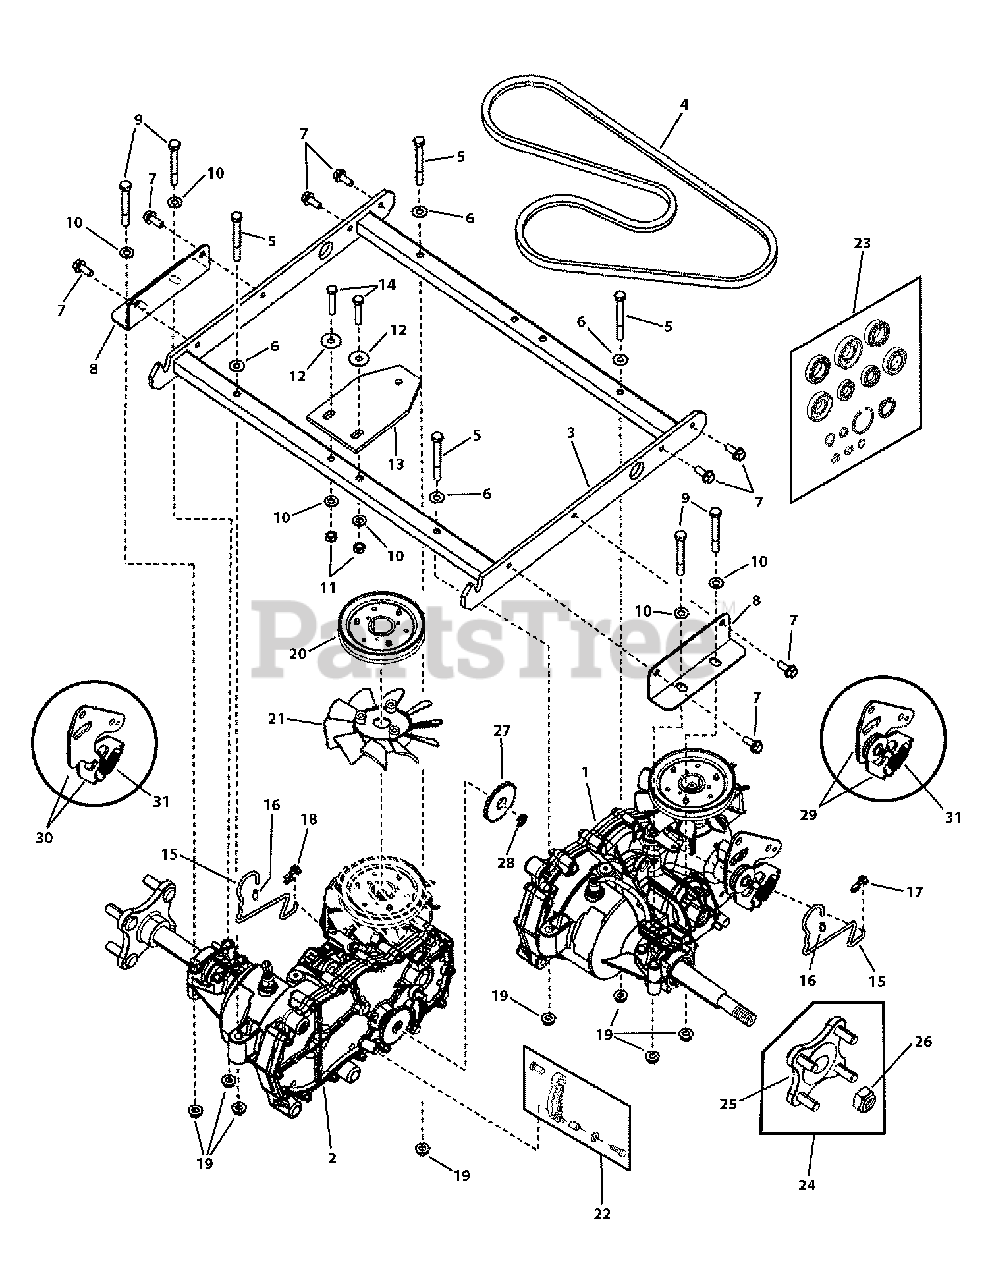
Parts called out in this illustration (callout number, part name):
1	TRANSMISSION- Hydro Gear, EZT LH ZT (ZC-AHBB-2A7B-1DPX)
2	TRANSMISSION- Hydro Gear, EZT RH ZT (ZC-DHBB-2A7C-1DPX)
3	WELDMENT, Transaxle Support
4	V-BELT, Hydro Drive
5	SCREW, 5/16-18 x 3" Hex Head Cap, GR 5, YZ
6	SHIM WASHER, 5/16 I.D.
7	SCREW, 5/16-18 x 3/4" Hex Washer Self-Tap, YZ
8	BRACKET, Transaxle Support
9	SCREW, 5/16-18 x 2-3/4" Hex Head Cap, GR 5 YZ
10	WASHER, 5/16" Flat
11	NUT, 5/16-18 Hex Center Lock, YZ
12	FENDER WASHER, 5/16"
13	RUBBER, Anti-Rotation
14	SCREW, 5/16-18 x 1-3/4" Hex Head Cap, GR 5 YZ
15	ROD, Roll Release
16	CAP, Vinyl
17	CLIP, Rod End Clevis LH for .188 Dia. Rod
18	CLIP, Rod End Clevis RH for .188 Dia. Rod
19	NUT, 5/16-18 Hex Flange Center Lock
20	PULLEY, 4-1/2"
22	ASSEMBLY, Parking Brake Arm, Trans
23	KIT, Hydro Seal
24	KIT, Hub Replacement (Incldes Ref. Nos. 25 & 26)
27	GEAR, Parking Brake, Trans
28	E-CLIP, Trans Parking Brake
29	KIT, LH Arm Control
30	KIT, RH Arm Control
31	SPRING, Extension (used only on Hydro Gear P/N ZC-AHBB-2A7B-1DPX & ZC-DHB-2A7C-1DPX)
31	SPRING, Extension (used only on Hydro Gear P/N ZC-AHBB-2ADB-1DPX & ZC-DHB-2ADC-1DPX)
